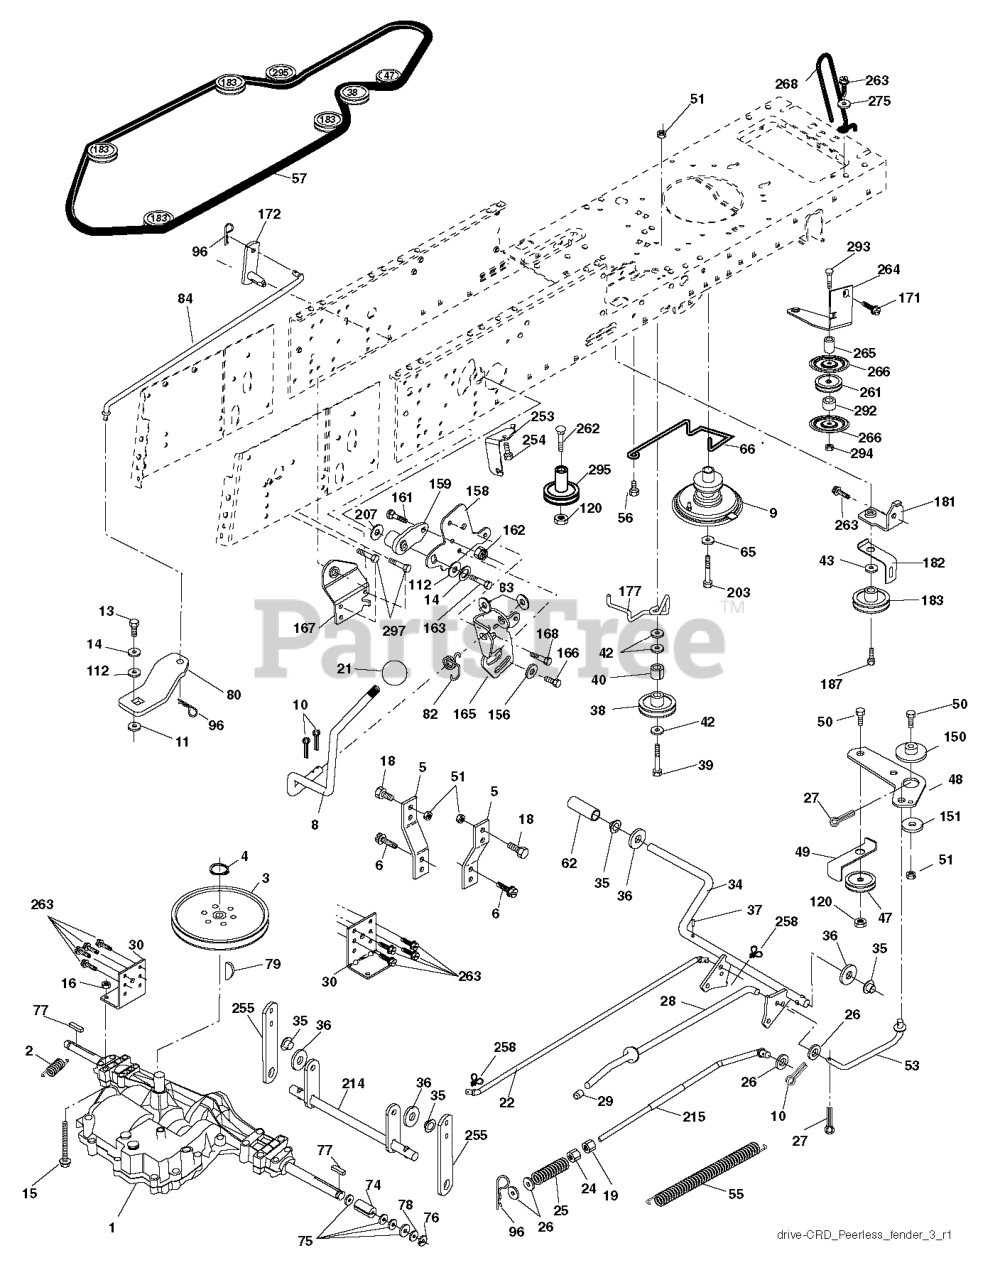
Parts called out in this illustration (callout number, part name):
2	SPRING,BRAKE RETURN
3	PULLEY
4	RETAINING RING LT
5	STRAP TORQUE
6	SCREW 5/16"
8	ROD SHIFT FENDER ADJUST LT
10	PIN COTTER
11	WASH-SHFT PLT LT
13	BOLT 1/4-28X3/4
14	LOCKWASHER
15	BOLT HEX 5/16-18 GR 5
16	NUT.71038.31-18.HEX.NYLOCK
19	NUT
21	KNOB T (1/2-HOLE)
22	ROD
24	NUT
25	SPRING ROD LT
26	WASHER
27	COTTER PIN
28	ROD, PARKING BRAKE
29	PLUNGER CAP
30	BRKT, MOUNT TRNSAXLE
34	SHAFT, FOOT PEDAL
35	BEARING.NYLON
37	DRIVE PIN
38	PULLEY.FLAT
42	WASHER
47	IDLER PULLEY
48	BELLCRANK, CLUTCH
49	RETAIN BELT
50	BOLT.3/8-16X1.50
53	LINK.CLUTCH.7.66.2005
55	SPRING, RETURN LT
56	SCREW.3/8-16
57	V-BELT 113"
62	PEDAL COVER T
65	LOCKWASHER
66	KEEPER BELT ENGINE
74	SPACER AXLE
77	SQUARE KEY
79	KEY STD (1373) DANA
82	SHIFT SPRING
83	WASHER
96	RETAINER M
120	NUT LOCK FLG 3/8-16 UNC
150	BUSHING.BELLCRANK.GRD.DR
151	WASHER 12/32X2X10GA
156	WASHER.SRRTD.5/16
158	BRACKET
159	RB HUB.SHIFT
161	BOLT
162	NUT.CROWNLOCK.1/4
165	RP BRACKET
166	CAPSCREW.HXHD.FLG.5/16-18X.625
167	BRACKET.SUPT.SHIFT.CRD
168	BOLT.SHOULDER.5/16-18X
172	SHAFT
181	BRACKET
182	BELT GUIDE
183	PULLEY.V-IDLER.
187	BOLT.5/16-18X1.25
203	BOLT.HEX.7/16-20 X 5
207	WASHER NYL
214	LEVER
254	SCREW 3/8-16X1
255	SHAFT
258	CLIP RETAINER
261	FLAT IDLER PULLEY
263	SCREW, 3/8-16X3/4
266	PROTECTOR
268	GUARD MUFFLER
275	WASHER
292	SPACER
293	BOLT.RDHD SQNK 3/8-16 X 3-1/2
294	NUT.HEX.3/8-16
295	PULLEY IDLER COMPOSITE
297	SCREW LT.3/8-46X5/8
